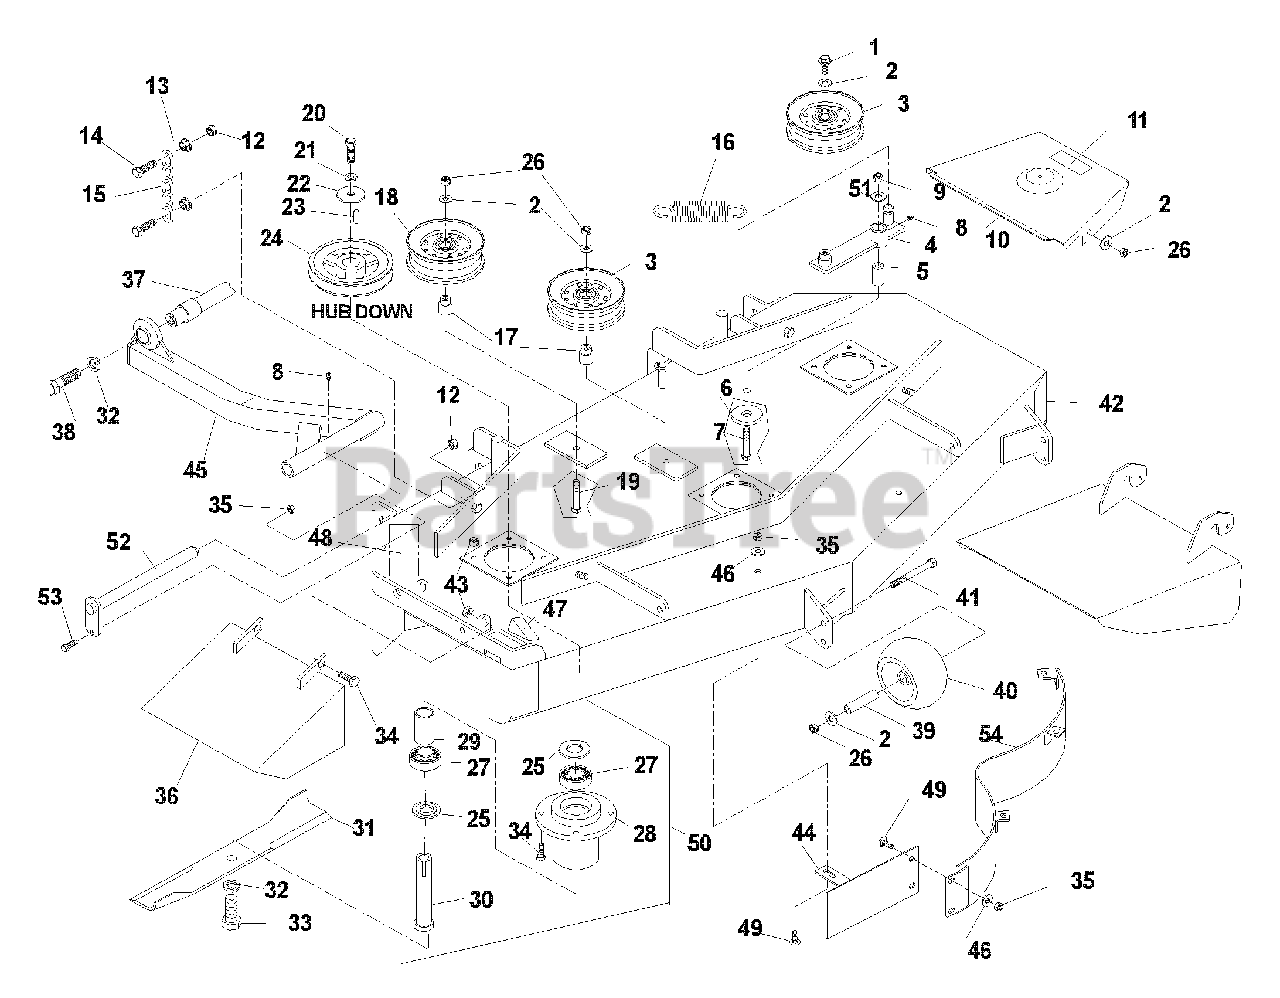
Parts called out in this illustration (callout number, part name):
1	HCS 3/8C X 1 SERRATED HD
2	WASHER 3/8 FLAT
3	IDLER PULLEY
5	PIVOT BUSHING
6	SUPPORT WASHER
7	HCS 1/2C X 3 1/4
8	ZERK
9	NUT 1/2C NYLOC
10	BELTSHIELD
11	DECAL, NO STEP
12	NUT 7/16C CENTERLOCK
13	7/16C WHIZ NUT
14	HCS 7/16C X 1 1/2
15	LIFT CHAIN
17	IDLER BUSHING
18	IDLER PULLEY(TALL)
19	HCS 3/8C X 2 3/4
20	HCS 7/16F X 1 1/2
21	LOCKWASHER 7/16
22	HEAVY WASHER
23	KEY 1/4 SQ. X 1 1/8
25	COMBO SPACER
26	NUT 3/8C NYLOC
27	BEARING
31	16 1/4" BLADE
32	LOCKWASHER 5/8
33	HCS 5/8F X 1 1/4
34	HCS 5/16C X 1 1/4
35	NUT 5/16C CENTERLOCK
36	DEFLECTOR CHUTE
37	STRUT MOUNT
38	HCS 5/8C X 2 GR.5
40	ANTI-SCALP ROLLER
41	HCS 3/8C X 3 1/2
42	DECK W/DECALS
43	NUT 5/16C, NYLOC
44	CENTER BAFFLE
45	STRUT - RT
46	5/16 FLAT WASHER
47	DECAL, CPSC
48	DECAL, DANGER
49	CARRIAGE BOLT
50	COMPLETE HOUSING
51	WASHER 1/2 FLAT
53	HCS 5/16C X 3/4
54	MAIN BAFFLE
